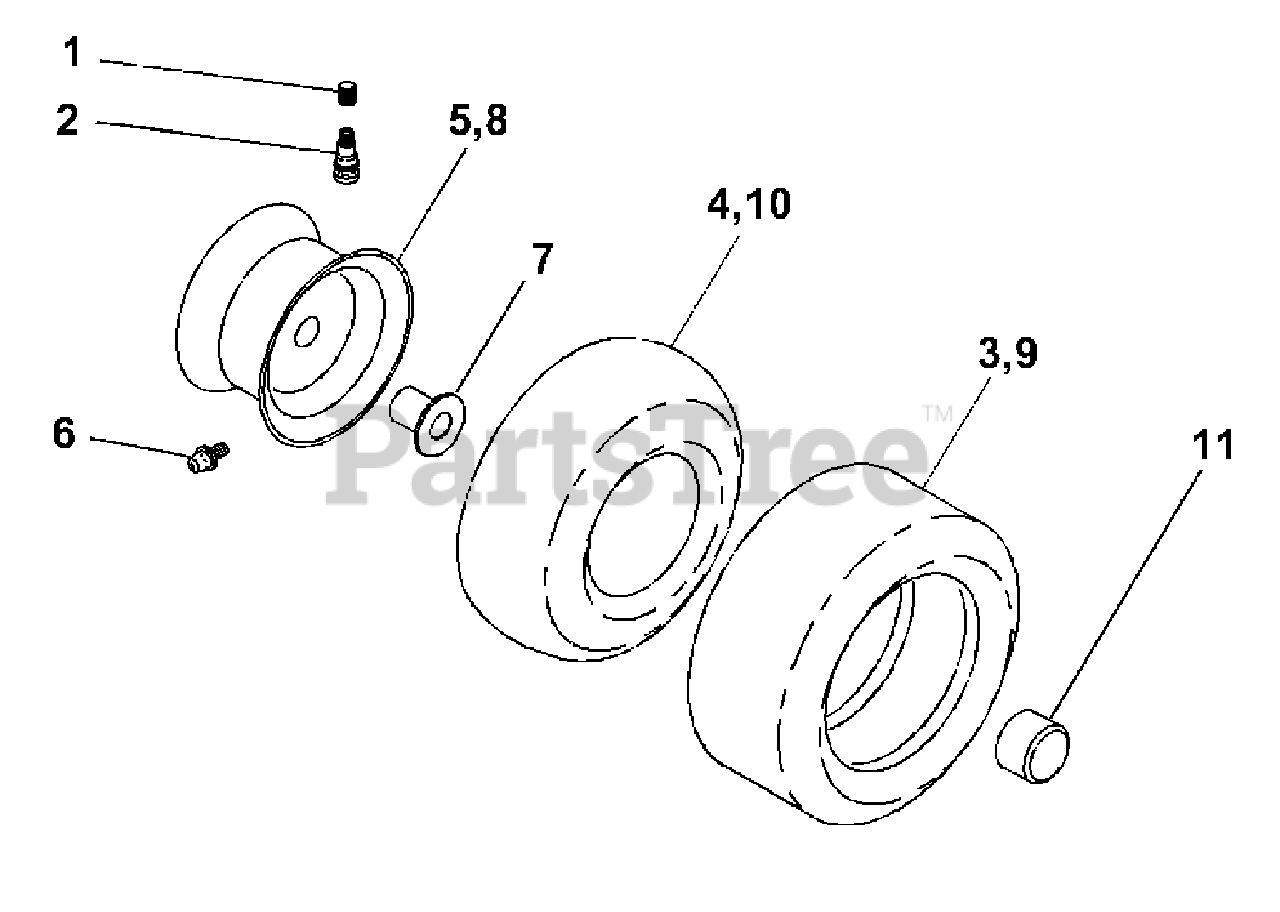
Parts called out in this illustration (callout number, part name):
1	Cap Valve Tire
2	Stem Valve
3	Tire F Ts 15 X 6 0 - 6 Service
4	Tube Front
5	Rim Asm 6" front Silver Service
6	Fitting Grease
7	Bearing Flange
8	Rim Asm 8" rear Silver Service
9	Tire R Ts 20 x 10-8 C Service
10	Tube Rear
11	Cap Axle Blk 1 50 X 1 00
